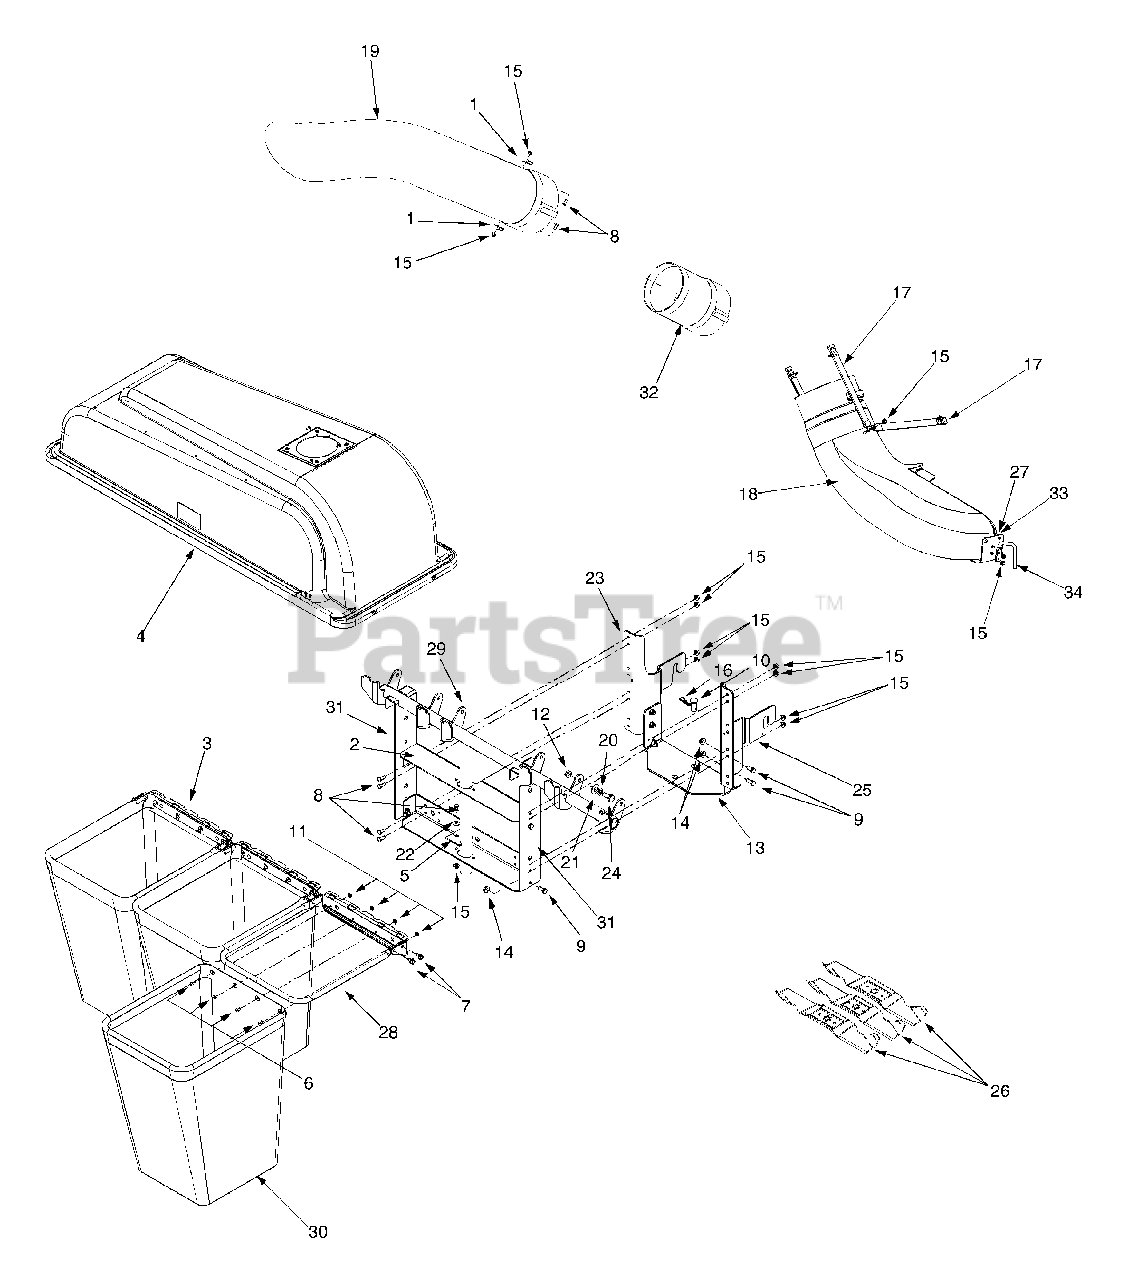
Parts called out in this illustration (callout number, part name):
1	Retainer Hook Bracket
4	Cover Assembly Complete
6	Screw, #10-24 x .5
7	Self Tapping Screw, 5/16-18 x .625
8	Hex Cap Screw, 1/4-20 x .62
9	Hex Cap Screw, 5/16-18 x .75
11	Hex Sems Nut, 10-24
12	Hex Flange Lock Nut, 3/8-16
14	Hex Flange Lock Nut, 5/16-18
15	Hex Flange Lock Nut, 1/4-20
16	Internal Cotter Pin, .148 x 3
17	Retainer Strap Assembly
18	Discharge Chute
19	Chute Tube
20	Flat Washer, .51 x .75 x .033
21	Belleville Washer
22	Bell Washer, .265 x .75 x .062
24	Shoulder Screw, .50 x .27, 3/8-16
26	High Lift Blades 18.50"
27	Hex Washer Screw 1/4-20 x 1.0
32	Extension Tube
33	Flat Washer .28 ID x .74 OD
34	Mounting Rod
